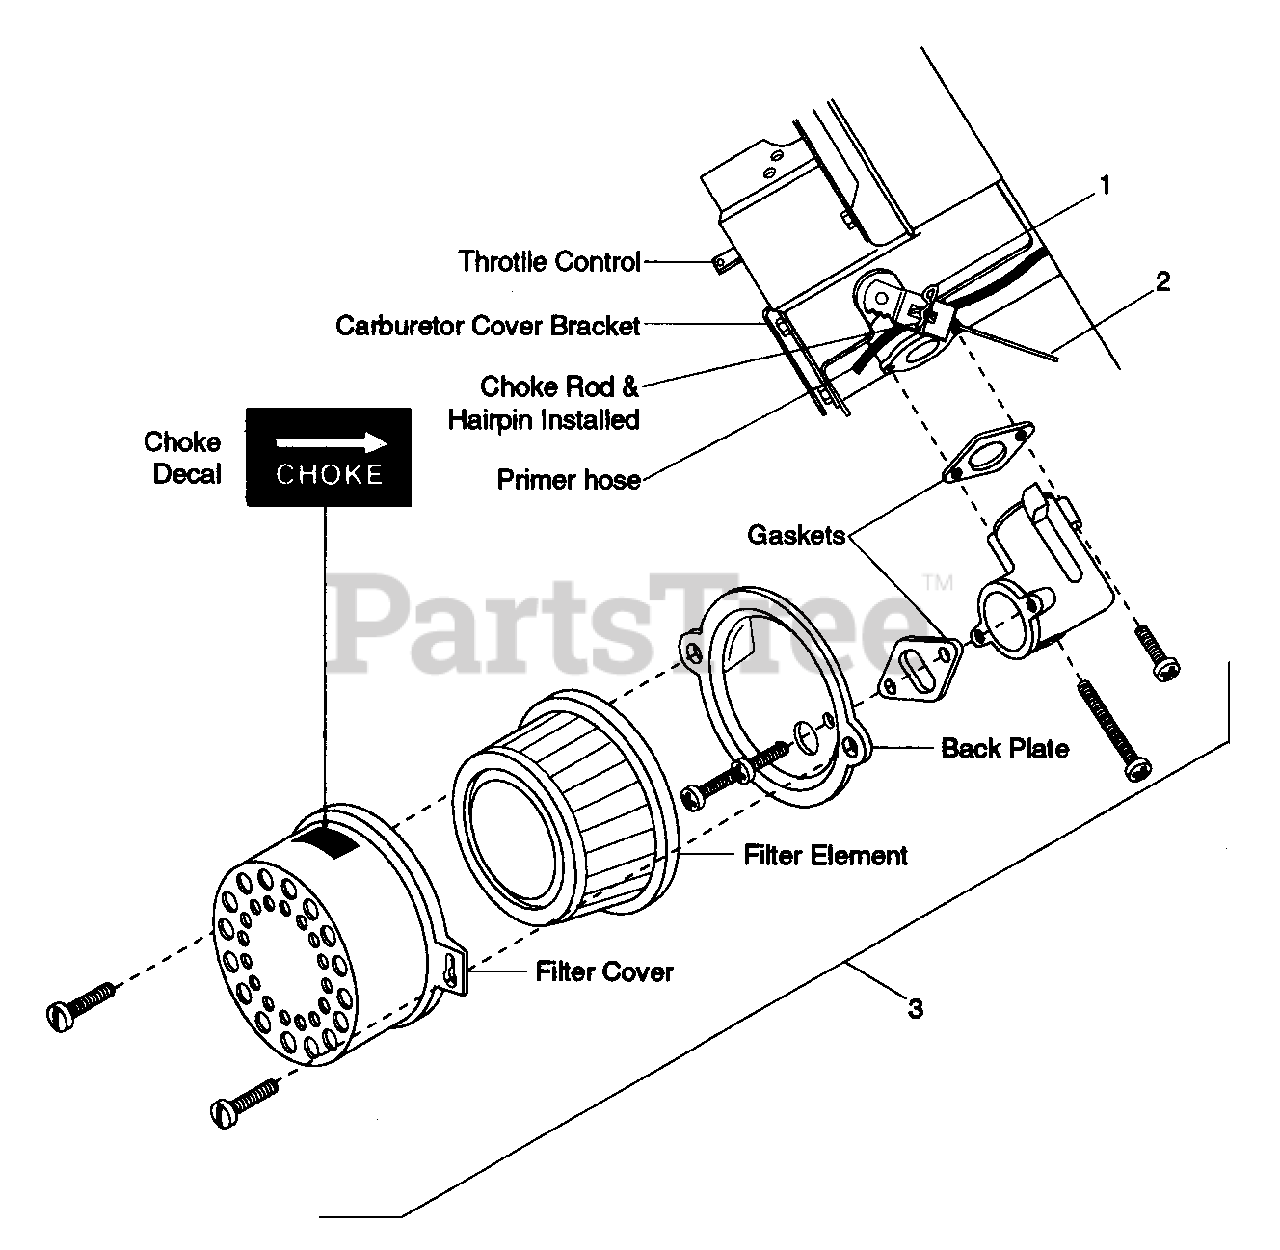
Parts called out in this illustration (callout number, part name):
1	PIN-HAIR INT .06X.18X.77
2	CHOKE ROD
3	AIR CLEANER KIT
